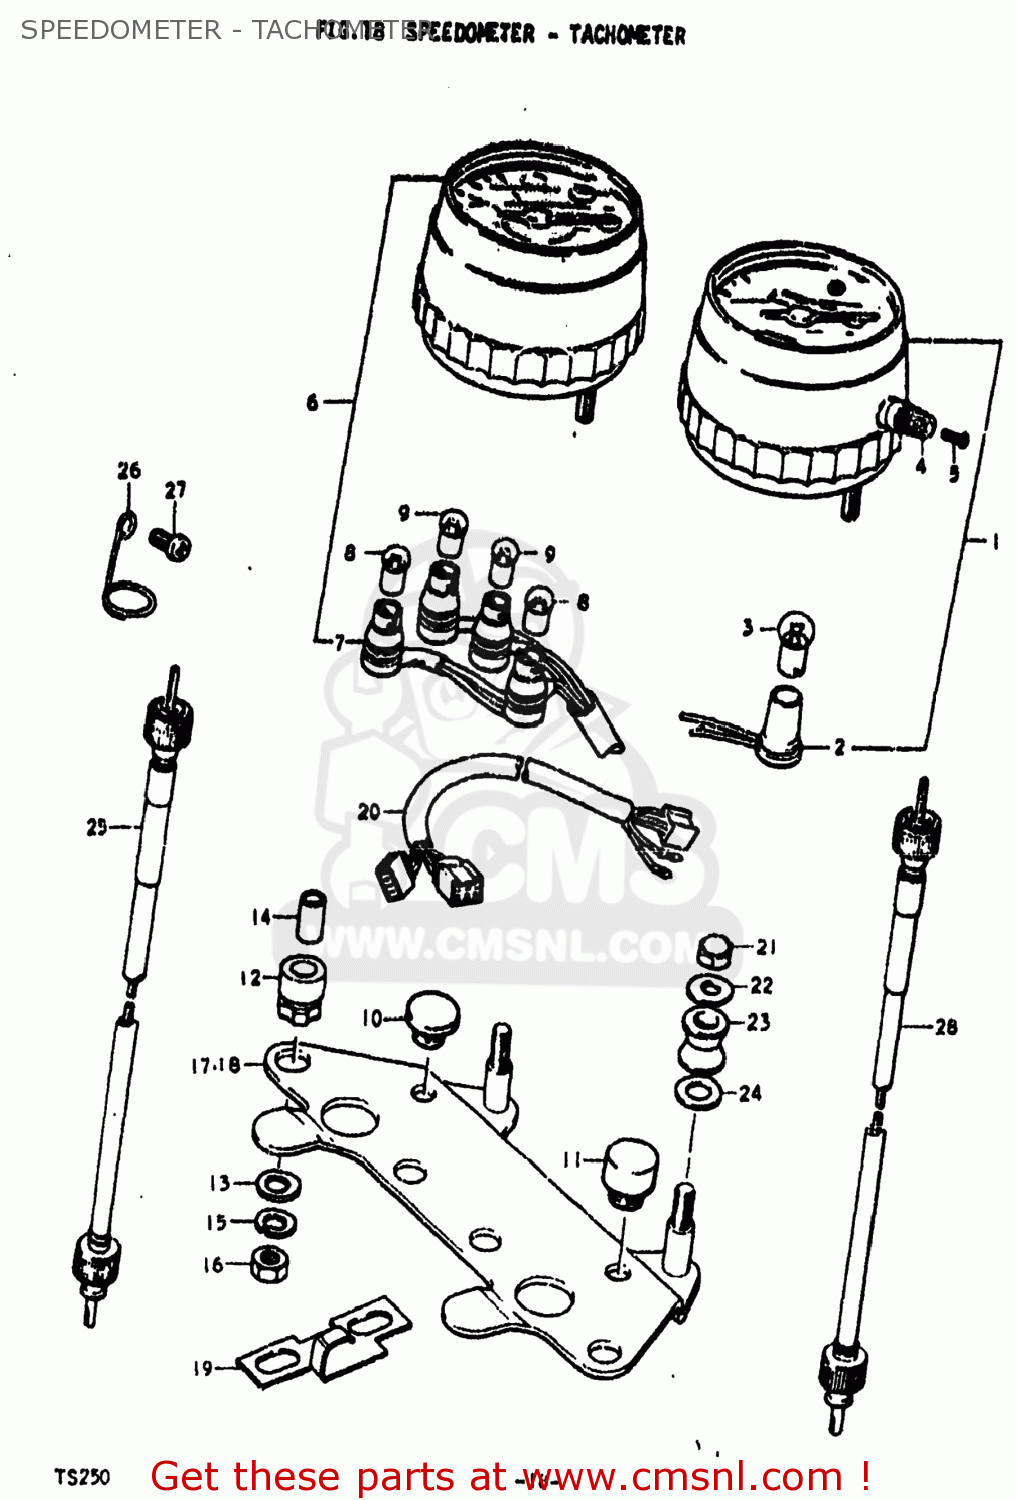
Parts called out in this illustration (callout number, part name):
1	SPEEDOMETER ASSEMBLY
2	SOCKET,METER
3	BULB(6V/3W)
5	ROTOR,SPEED
6	METER,TACHOMETER
7	SOCKET,METER
8	BULB(6V/3W)
9	BULB(6V1.7W,STANLEY,A61A)
10	CUSHION,METER NO.1
11	CUSHION,METER
12	CUSHION,METER
13	WASHER
14	SPACER,METER
15	LOCK WASHER
16	NUT
17	BRACKET,METER
18	BRACKET,METER
19	COVER,METER,UNDER
21	NUT
22	WASHER
23	CUSHION
24	WASHER
25	CABLE ASSEMBLY,TACHOMETER
26	CLIP,TACHOMETER CABLE
27	SCREW
28	CABLE ASSEMBLY,SPEEDOMETER
